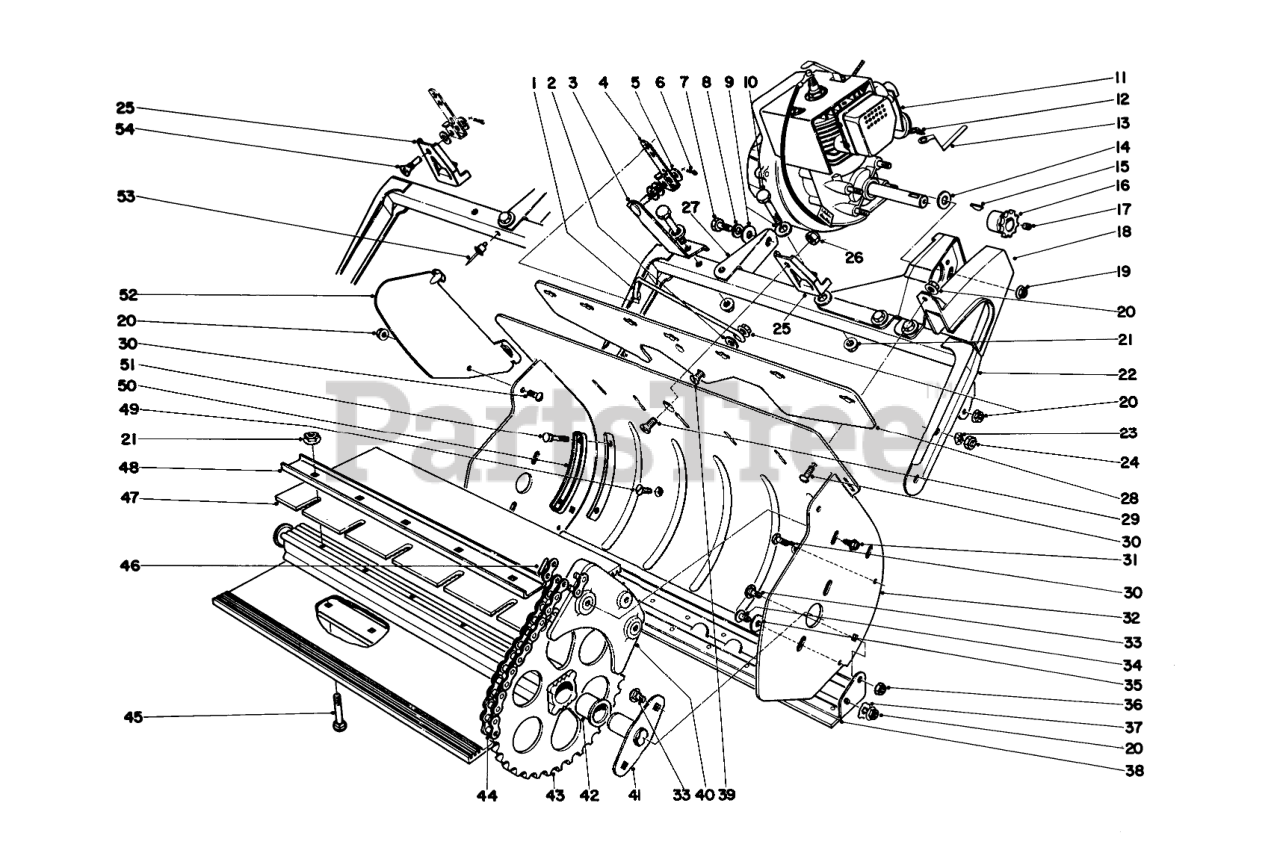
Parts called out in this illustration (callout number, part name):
1	Linkage Vane Adj.
2	WASHER-FLAT
3	Vane Adj. Bracket
4	Bracket-Vane Adj.
5	WASHER-FLAT
6	PIN-COTTER
7	SCREW-HH
8	WASHER-LOCK/EXT
9	WASHER-FLAT
10	SCREW-HH
11	Engine
12	Cotter Pin
13	Strap-Choke
14	WASHER-PLAIN
16	SPROCKET
17	SCREW-SET, HSH
18	Chain Guard
19	NUT-HHF
20	NUT-LOCK, FLANGE
21	Nut
22	Frame Assy.
22	Frame Assembly
23	Washer
24	Nut
25	Stiffener
26	NUT-LOCK, NI
27	Bracket
28	Mount-Vane
28	Mount Vane
29	5/16-18X5/8 FLT HD MS
30	SCREW-PTH
31	Screw
32	Housing
33	SCREW-CARRIAGE
34	SCREW-HEAD, PAN
35	Washer
36	NUT-KEPS
37	Washer
38	Skid Assembly
38	Skid Assy.
39	10-24X1-1/8 FLT HD MS
40	Stripper
41	Rotor Shaft Assy.
42	Bushing
43	Sprocket & Tube (Incl. Ref. #42)
44	CHAIN
46	LINK-CONNECTING, NO. 35
47	Blade-Rotor
48	Strap-Reinforcing
48	Reinforcing Strap
50	Handle Plate
51	SCREW-CARR
52	Vane
53	RIVET
54	Screw
